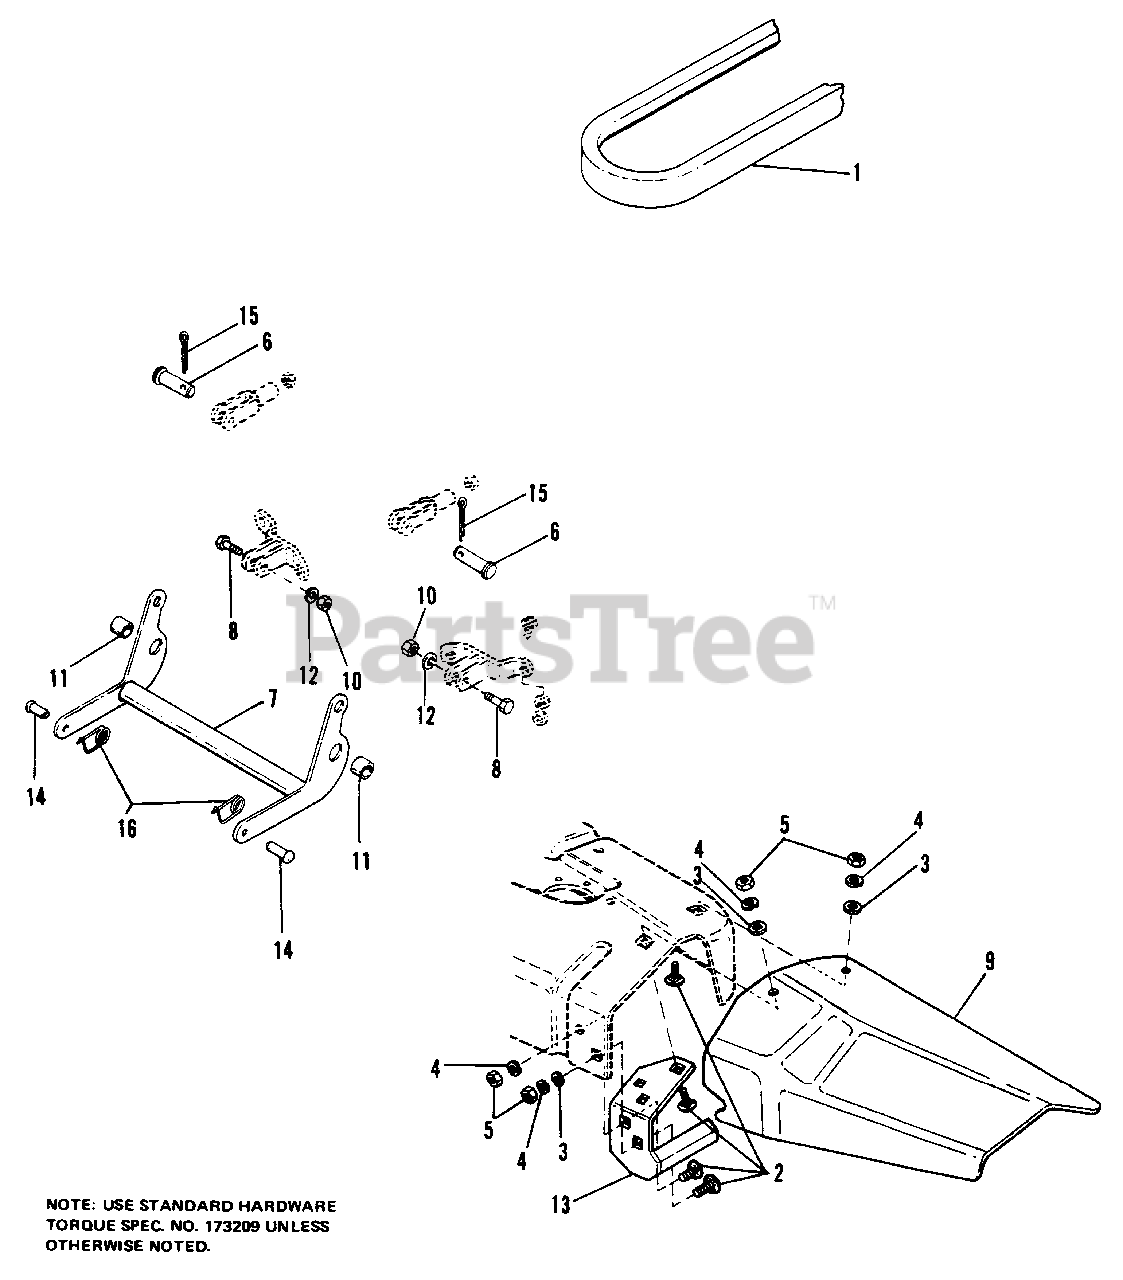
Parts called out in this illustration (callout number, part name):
1	BELT, V, PTO to Mower
2	BOLT, Carraige, 3/8-16 x 1-1/4
3	WASHER, Special
4	LOCKWASHER, 3/8
5	NUT, Hex, Full, 3/8-16
6	PIN, Yoke
7	ROCKER ARM ASSY
8	CAPSCREW, Hex Hd., 1/2-13 x 1-1/4
10	NUT, Hex, Full, 1/2-13
12	LOCKWASHER 1/2
13	GUARD ASSY, Stone
14	PIN
15	PIN, Cotter, 1/8 x 1
16	PIN, Clip
